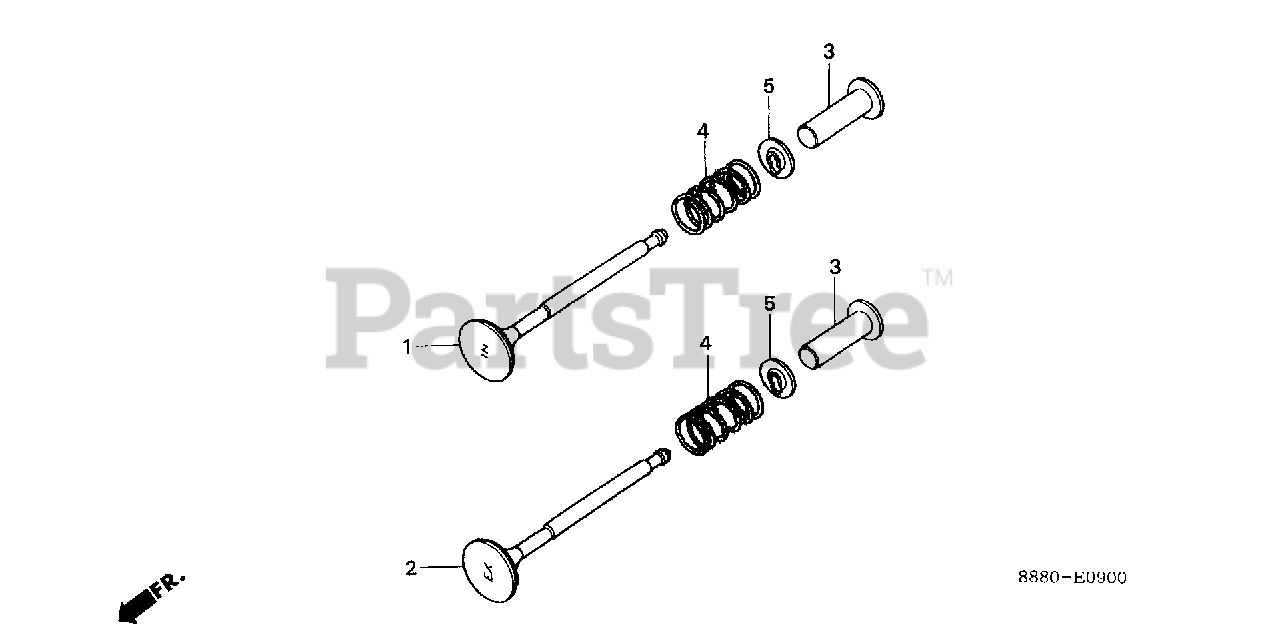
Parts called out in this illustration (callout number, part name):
1	VALVE, IN.
2	VALVE, EX.
3	LIFTER, VALVE (31.33)
3	LIFTER, VALVE (31.51)
3	LIFTER, VALVE (31.66)
4	SPRING, VALVE
5	RETAINER, VALVE SPRING
